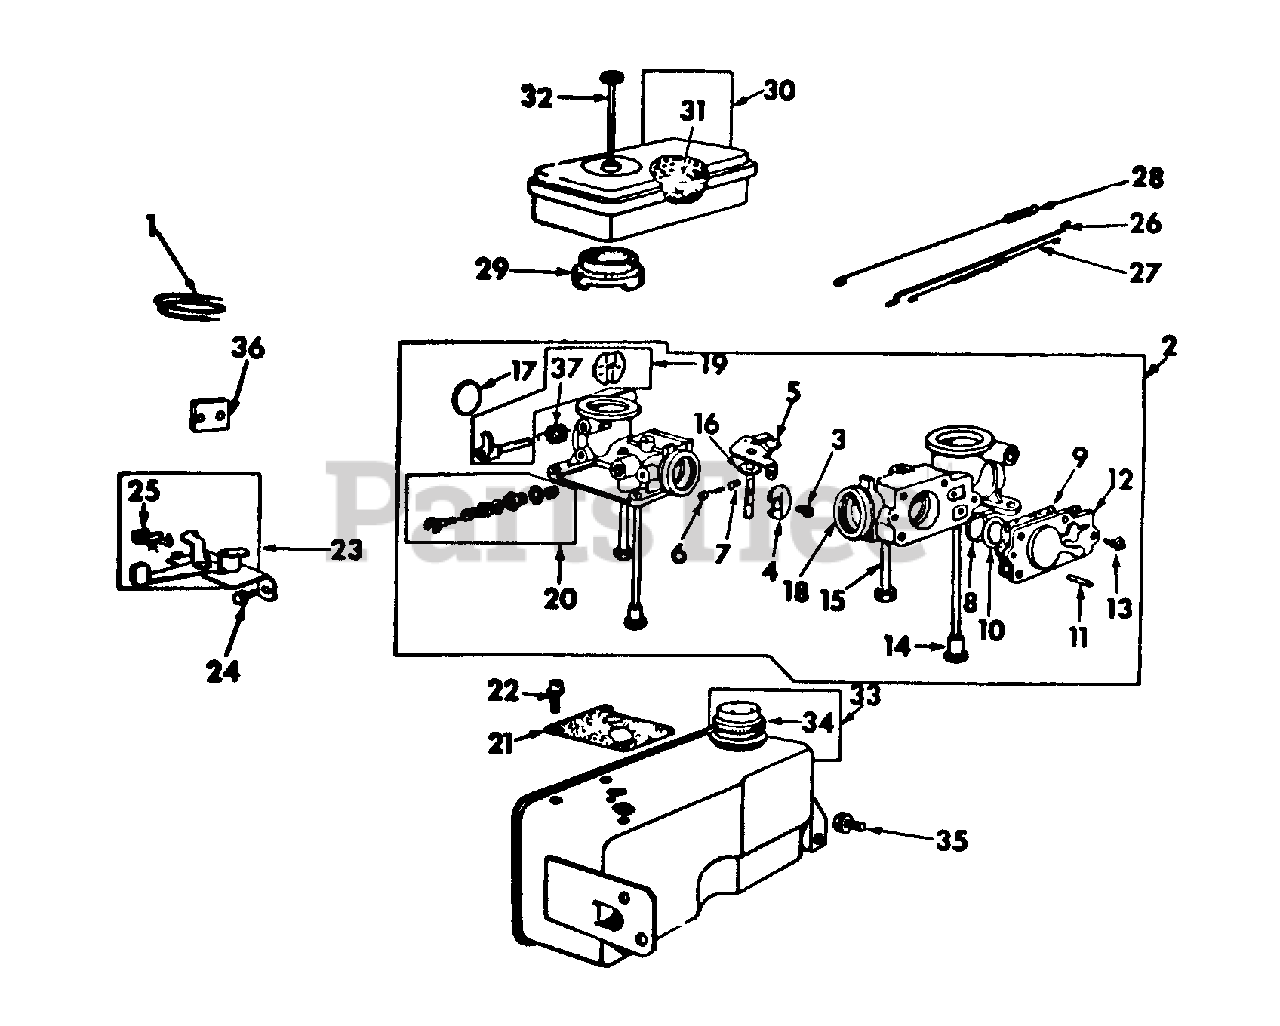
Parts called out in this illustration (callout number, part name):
1	WIRE, GROUND
2	CARBURETOR ASSY
3	SCREW, THROTTLE VALVE
4	VALVE, THROTTLE
5	SHAFT & LEVER ASSY, THROTTLE
6	SCREW, THROTTLE ADJ
7	SPRING, THROTTLE ADJ
8	SPRING, FUEL PUMP
9	DIAPHRAGM
10	CAP, SPRING
11	PIN, COVER
12	COVER, DIAPHRAGM
13	SCREW, COVER
14	SCREEN, FUEL PIPE HOUSING
15	PIPE, FUEL
16	WASHER, THROTTLE FELT
17	PLUG, 7/8 EXPANSION
18	SEAL, INTAKE TUBE
19	SHAFT & LEVER ASSY, CHOKE
20	KIT, NEEDLE VALVE
21	GASKET, TANK MTG
22	SCREW, CARBURETOR MOUNTING
23	PLATE, CARBURETOR CONTROL
24	SCREW, CONTROL PLATE MOUNTING
25	SWITCH, STOP
26	LINK, THROTTLE
27	SPRING, THROTTLE LINK
28	SPRING, GOVERNOR
29	GASKET, AIR CLEANER
30	CLEANER ASSY, AIR
32	SCREW, AIR CLEANER
33	TANK ASSY W/CAP, FUEL
34	CAP, FUEL TANK
35	SCREW, 1/4-20 X 1/2 ZND HEX-HD CAP
36	INSULATOR, TERMINAL
37	SPRING, CHOKE RETURN
